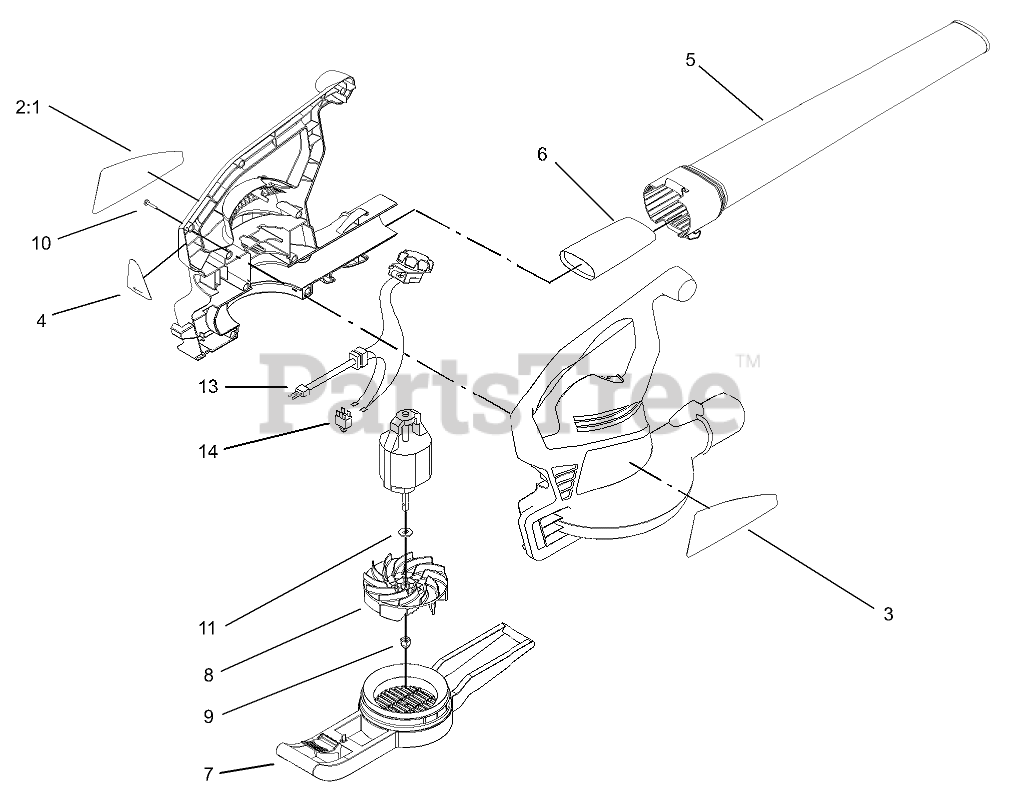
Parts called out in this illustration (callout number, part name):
2	Decal-Serial
2:1	Label Stock-Serial
3	Decal-Superblower
4	DECAL-LOCK, CORD
5	TUBE-BLOWER
6	TUBE-INSERT
7	COVER-INLET
8	Impeller-Magnesium
9	NUT-HEX
10	SCREW-PPH
11	WASHER
13	Wire Harness ASM
14	SWITCH-INTERLOCK
